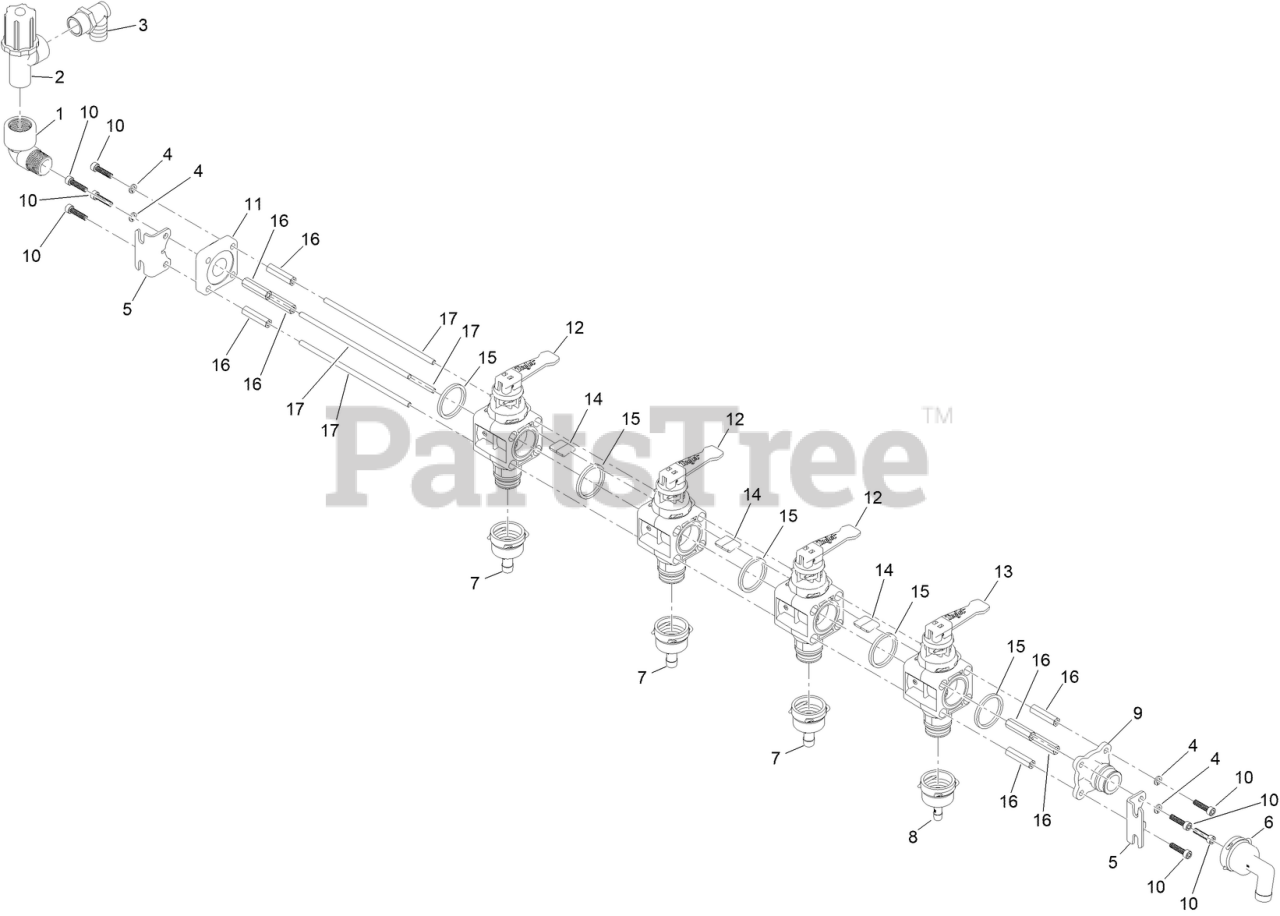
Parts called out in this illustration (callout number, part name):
1	ELBOW-90DEG
2	VALVE-THROTTLE
3	FITTING-ELBOW, 90
5	BRACKET-MOUNT
6	KIT-HOSE BARB, 3/4 90, QC
7	Kit-1/2 Hb, STR, Qc
8	KIT-3/8 HB, STR, QC
9	Adaptor-Male Qc Bolted Flanged
10	Screw-Hscs 6 MM X 25.0 MM SS
11	CAP-END, 3/4 NPT, FEMALE
12	ASM-Valve Section, Grey
13	ASM-VALVE SECTION, BLACK
14	Alignment Piece
16	M6X1 Metric Hex Stand-Off
17	M6X1 THREADED ROD
